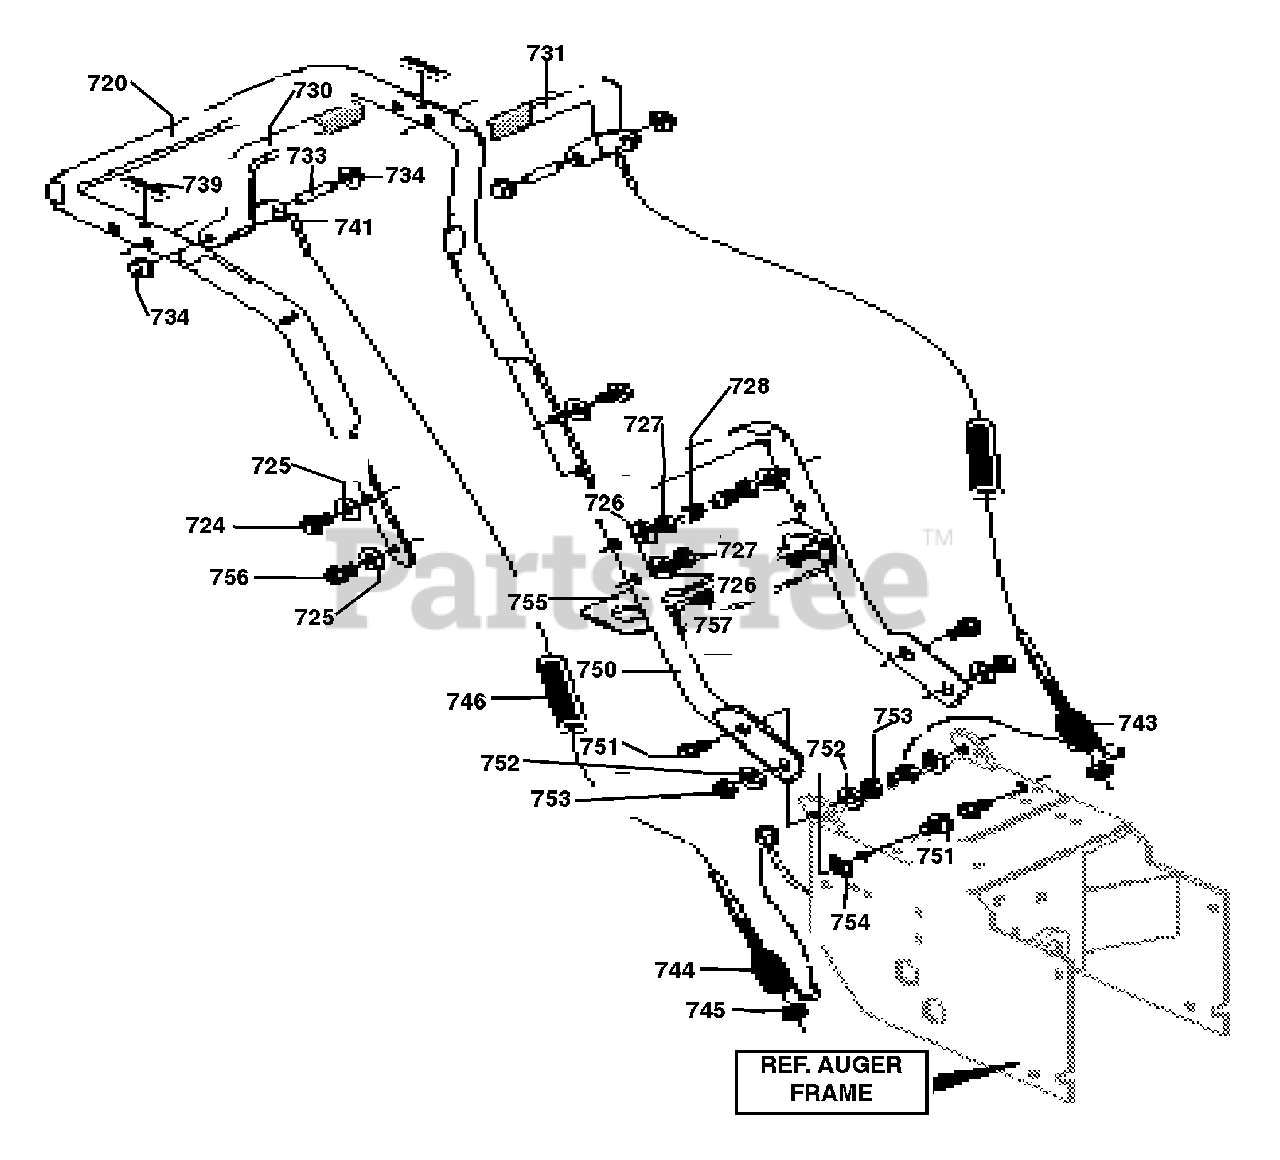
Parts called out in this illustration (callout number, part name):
720	HANDLE, UPPER
724	SCREW, 5/16-18 X 2.75
725	WASHER, FLAT .344 X .69 X .065
726	WASHER, .328 X .60 X .09
727	NUT, 5/16-18 REGHEX
728	STOP, PLASTIC 5/16
730	KIT FOR 307974
731	KIT FOR 307974
733	PIN, PIVOT
734	NUT, PUSH ON CAP
741	CABLE, CLUTCH
743	SPRING, TENSION
744	SPRING, AUGER CLUTCH
745	NUT, 1/4-20
746	BOOT, CLUTCH SPRING
750	HANDLE, LOWER
751	SCREW, 5/16-18 X 1.00
752	WASHER, .328 X .60 X .09
753	NUT, 5/16-18 REGHEX
754	PUSHNUT, 5/16
755	BRACKET,GEAR SELECTOR
756	SCREW, 5/16-18 X .75
757	SCREW, PLASTIC
